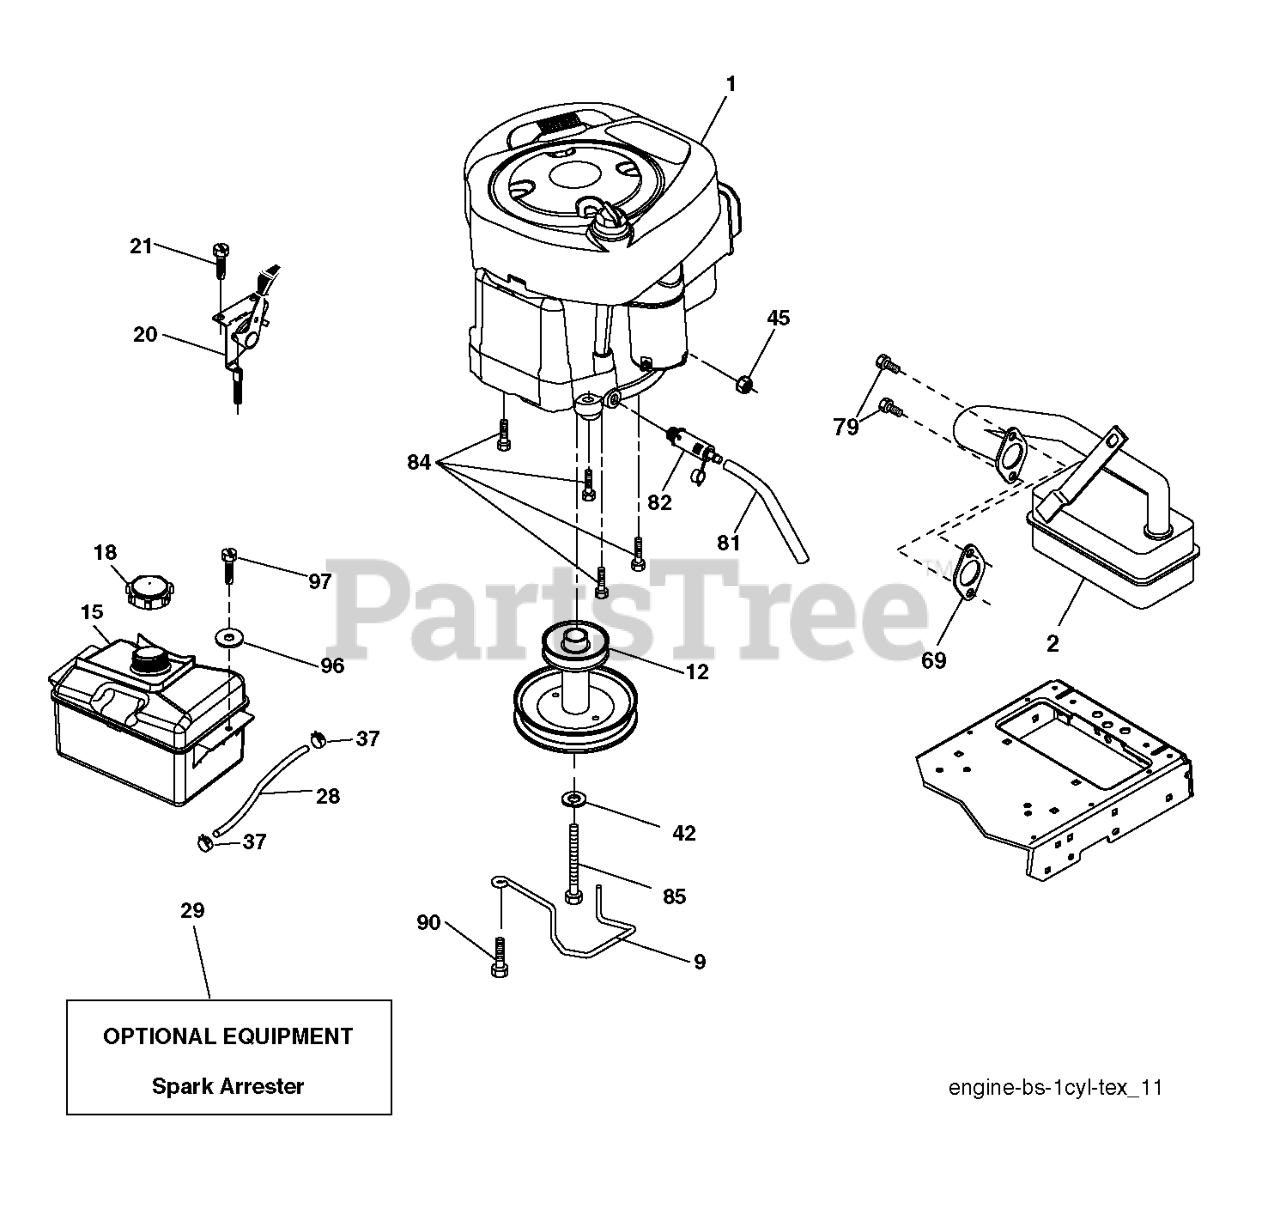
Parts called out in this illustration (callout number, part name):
2	MUFFLER.B&S.MODEL.21.11HP.OHV
9	KEEPER.BELT.ENGINE.3.25 (3 2)
12	PULLEY.ENG.CL.MECH.SLVR.LT/YT
15	RP TANK FUEL FRT 1.5 GAL
18	FUEL CAP
20	CONTROL.TH/CK.C.
21	SCREW.#10 X 0.750.BOS
28	LINE.FUEL.20
29	KIT.SPARK ARRESTOR 794945 B&S
37	HOSE CLAMP
42	LOCKWASHER
45	NUT
69	REPL BY 532 27 22-93
79	SCREW.SOCKET HD.5/16-1
81	TUBE, DRAIN OIL ASM.
82	PLUG DRAIN OIL EASY
84	SCREW.3/8-16
85	BOLT HEX 7/16-20X4-1/4"
90	SCREW 3/8-16X1
97	SCREW HEXWSHR 1/4-20X3/4
